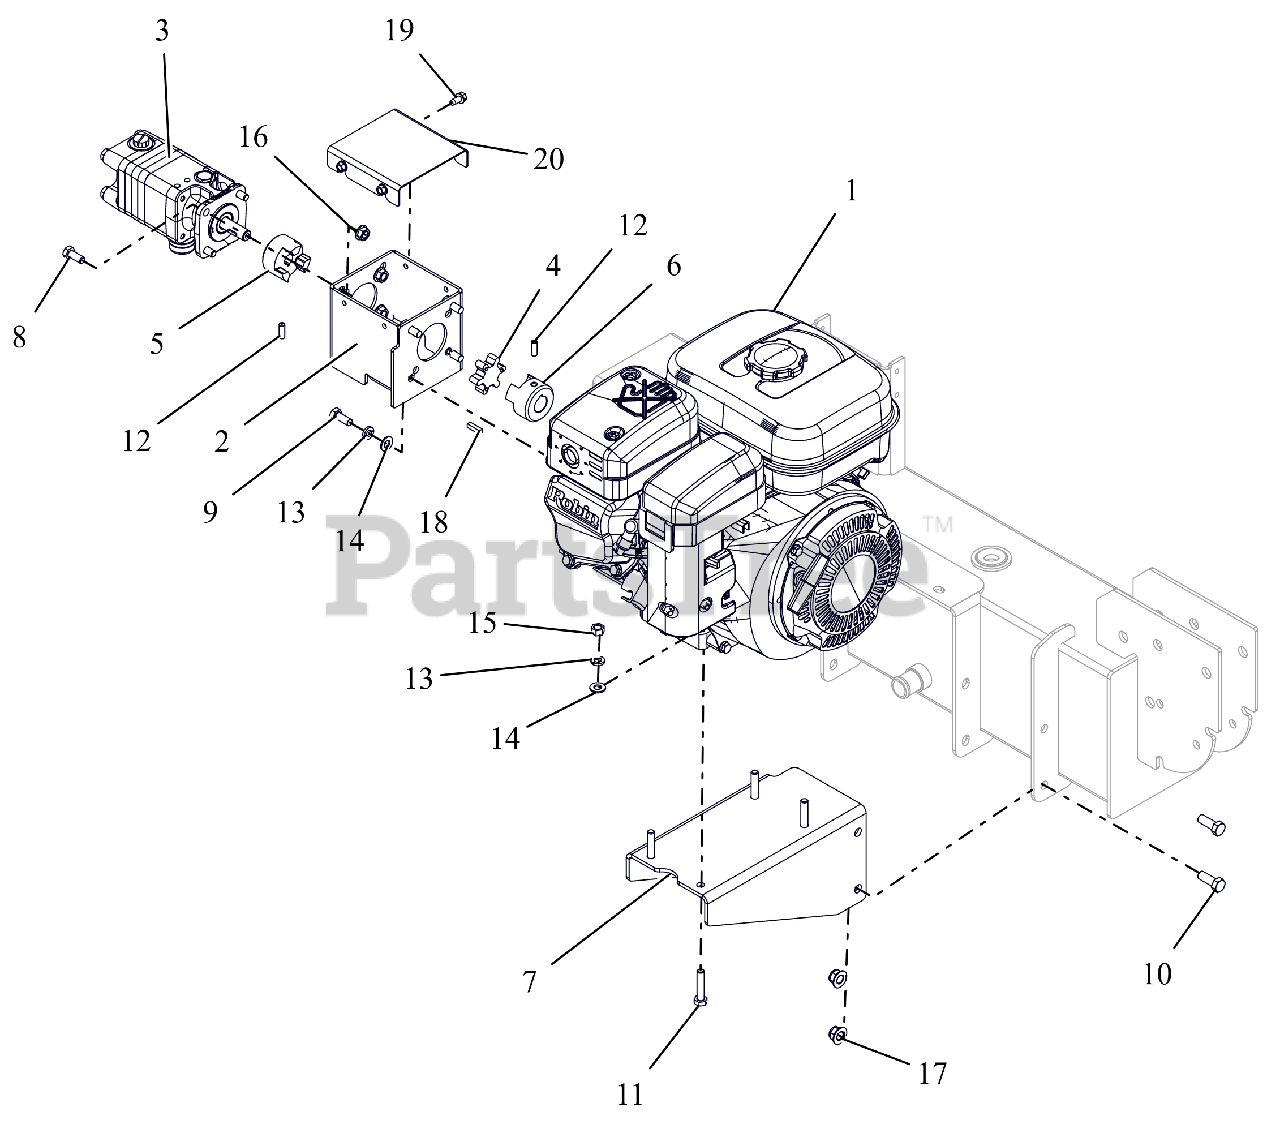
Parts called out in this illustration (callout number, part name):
1	ENGINE,SUBARU EX210DT1032-MP
2	WLDMT, PUMP MOUNT BRKT
3	PUMP,SPLITTER-13 GPM
4	SPIDER - URETHANE
5	COUPLER - DRIVE 1/2"
6	COUPLER - DRIVE, 3/4"
7	MOUNT-ENGINE
8	@BLT-HEX .31-18X.75 GR5 YWZC
9	BLT-HEX .31-24X.75 YWZC GR5
10	@BLT-HEX .38-16X1.00 GR5 YWZC
11	@BLT-HEX .31-18X1.50 GR5 YWZC
12	SCR,SET .25-20X.75 PCPT SH
13	WSHR-LK .312X.097 HVY YWZC
14	@WSHR-FL-STL.344X.688X.065YWZC
15	@NUT-HEX .31-18 YWZC
16	@NUT-LK-TOP-FLG .31-18 YWZC
17	@NUT-LK-NYL-FLG .38-16 YWZC
18	KEY-SQ .188X.75X.188
19	SCR-TAP .25-20X.50 HWH TR YWZ
20	COVER W/DECALS
